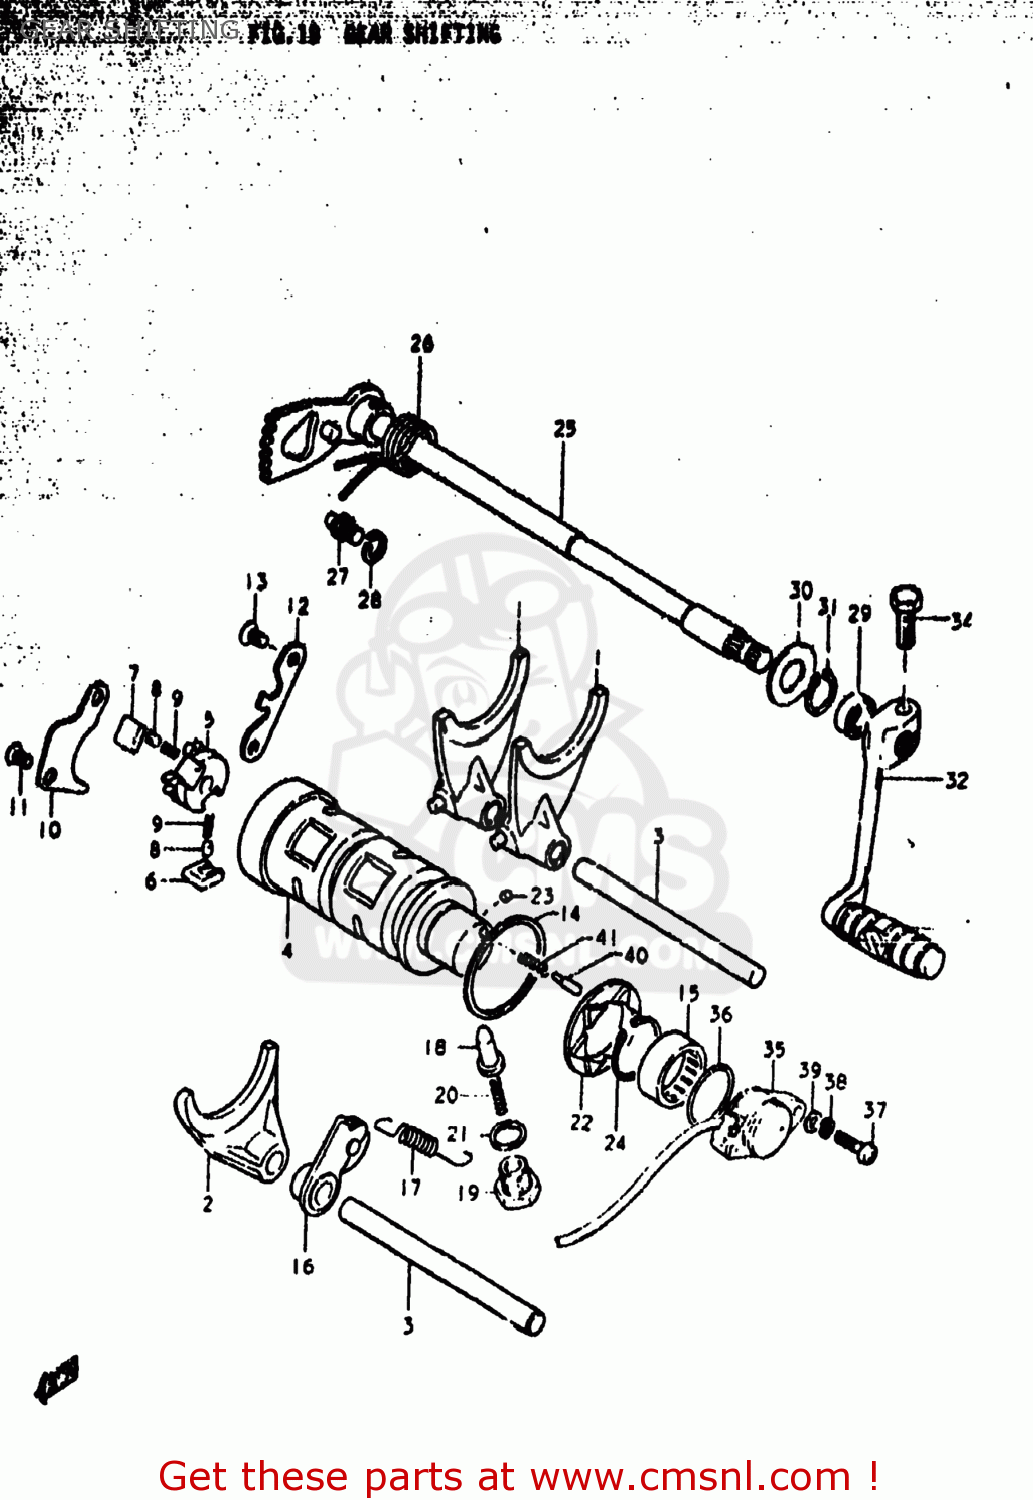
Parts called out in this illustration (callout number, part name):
1	FORK,GEAR SHIFT NO.1
2	FORK,GEAR SHIFT NO.3
3	SHAFT,GEAR SHIFT FORK
4	CAM,GEAR SHIFT
5	RETAINER,GEAR SHIFT CAM
6	PAWL,GEAR SHIFT NO.1
7	PAWL,GEAR SHIFT NO.2
8	PIN(5X8)
9	SPRING
10	LIFTER,GEAR SHIFT PAWL
11	SCREW
12	GUIDE,GEAR SHIFT CAM
13	SCREW
14	WASHER(40X45X1)
15	BEARING(25X32X12)
16	STOPPER,GEAR SHIFT CAM
17	SPRING
18	STOPPER,GEAR SHIFT CAM NO.2
19	HOLDER,GEAR SHIFT CAM STOP SPR
20	SPRING
21	GASKET(14X19.2X2) (NAS)
22	PLATE,GEAR SHIFT CAM STOPPER
23	PIN 4X6
24	CIRCLIP
25	SHAFT,GEAR SHIFT
26	SPRING
27	STOPPER,GEAR SHIFT CAM
28	LOCK WASHER
29	OIL SEAL
30	WASHER (12.5X27X1.6)
31	SPRING,RETAINER
32	LEVER ASSY,GEAR SHIFT
33	RUBBER,GEAR SHIFT PEDAL
34	BOLT
35	TERMINAL BASE,NEUTRAL SWITCH
36	O-RING (D:2.4 ID:26.2)
37	SCREW 5X20
38	LOCK WASHER
39	WASHER
40	PIN(5X15.5)
41	SPRING
